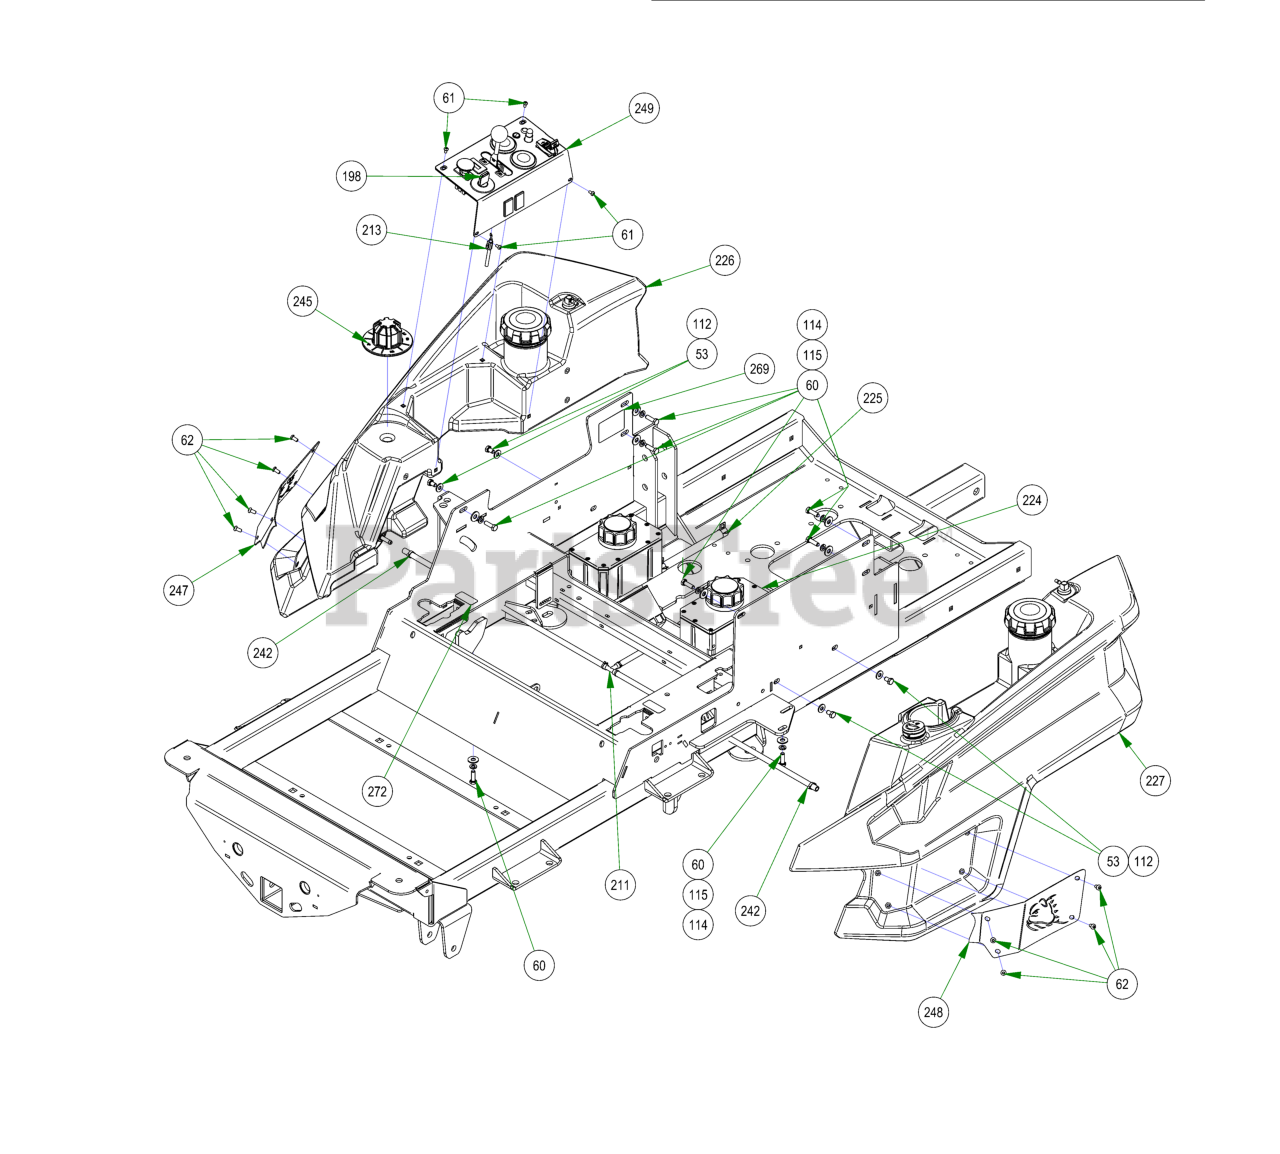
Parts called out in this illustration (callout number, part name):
53	5/16-18 X 1/2 HEX CAP SCREW (GR.5) ZINC
60	5/16-18 X 1 HEX CAP SCREW (GR.5) ZINC
61	10-32 X 3/8 BUTTON SOCKET CAP SCREW 18-8 STAINLESS STEEL
62	1/4-20 X 1/2 BUTTON SOCKET CAP SCREW 18-8 STAINLESS STEEL
112	1/4 USS FLAT WASHER (3/4 OD) ZINC
114	5/16 USS FLAT WASHER (7/8 OD) ZINC
115	5/16 SPLIT LOCKWASHER ZINC
129	.380 ID X .625 OD X 1.500 LGTH 2019 OUTLAW BRAKE HANDLE SPACER ZINC
136	1 3/4" Pulley Spacer
198	Ignition Key
211	2022 Renegade Diesel Fuel Line Assembly
213	Diesel Throttle Cable
224	LH Rogue Hydro Tank Assy
225	RH Rogue Hydro Tank Assy
226	2019 Right Renagade Fuel Tank (diesel)
227	2019 Left Renegade Fuel Tank (Diesel)
235	2022 Horizontal Diesel Frame
242	2 EAR CLAMP 12.5mm-15mm
245	2019 Deck Height Dial
247	2019 Outlaw Fuel Tank Insert - Right
248	2019 Outlaw Fuel Tank Insert - Left
249	Renegade Control Panel Assembly
269	Hydraulic Decal
272	Low Sulfer Decal Tier 4 Diesel
